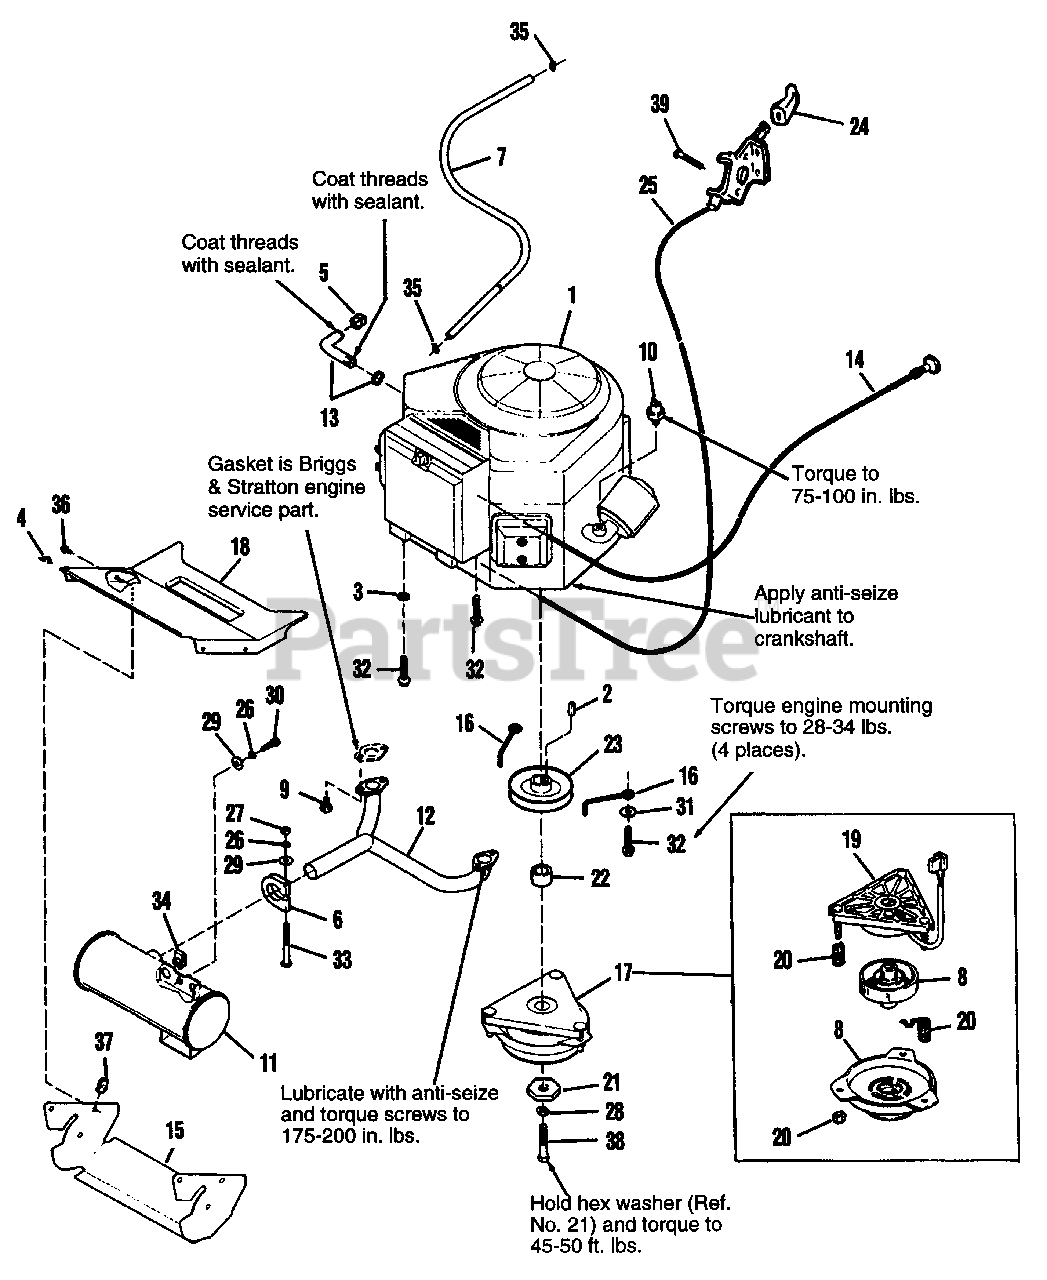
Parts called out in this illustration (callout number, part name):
2	KEY, Hi-Pro
3	LOCKWASHER, External Tooth
4	CLIP
6	CLAMP, Muffler
7	HOSE, Fuel, 45.5" Long
8	ROTOR ASSY./ARMATURE KIT
9	SCREW, Metric
10	SWITCH, Oil Pressure
11	MUFFLER ASSY.
12	MANIFOLD, Exhaust
14	CABLE, Choke Control
15	DUCT, Lower Muffler
17	ELECTRIC CLUTCH (Incl. Ref. Nos. 8, 19 & 20)
18	DUCT, Upper Muffler
19	FIELD ASSY., Clutch
20	SPRING & NUT KIT
23	PULLEY ASSY.
24	KNOB, Throttle
25	THROTTLE & CABLE ASSY.
26	LOCKWASHER, 5/16
27	NUT, Hex, Full, 5/16-18
28	LOCKWASHER, 7/16
29	WASHER, Plain, 11/32
30	CAPSCREW, Hex Hd., 5/16-18 x 1
31	WASHER, Plain, 13/32
32	SCREW, Taptite, 3/8-16 x 1-1/2
33	CARRIAGE BOLT, 5/16-18 x 2-3/4
34	NUT, Pal, 5/16-18
35	CLAMP, Hose
36	SCREW, Flange Whiz, 1/4-20 x 5/8
37	NUT, Pal, 1/4-20
38	CAPSCREW, 7/16-20 x 4
39	SCREW, Plastite, 1/4-10 x 1/2
